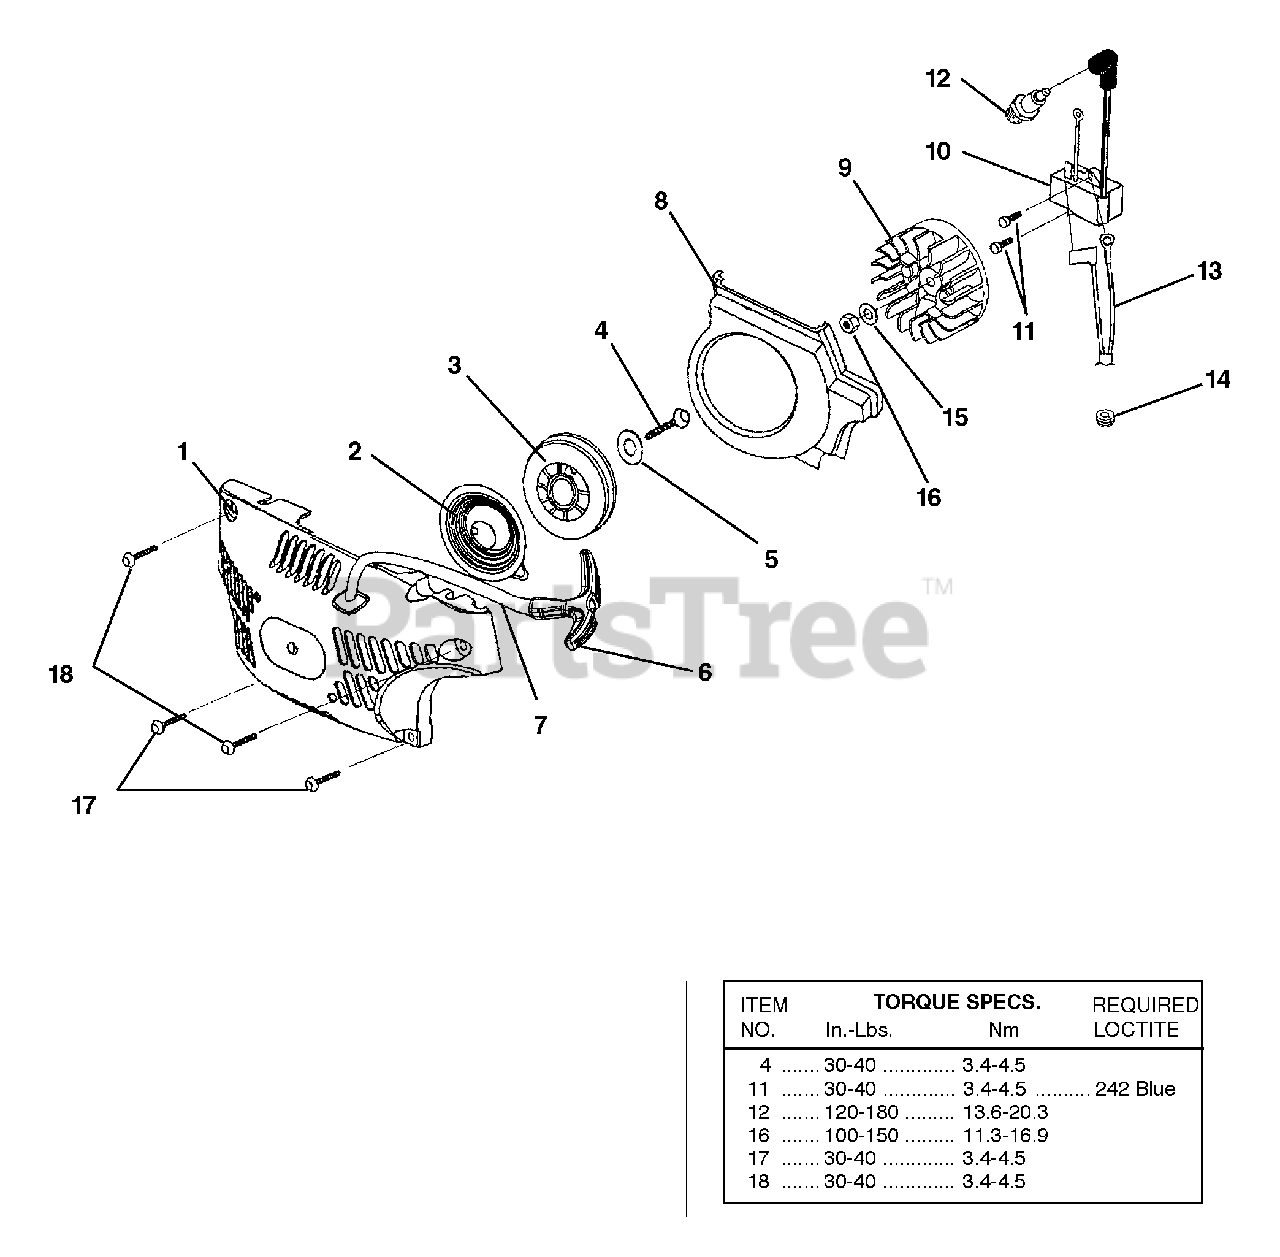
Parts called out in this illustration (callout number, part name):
1	Starter Kit
2	Spring & Container
3	Pulley, Starter
4	Screw, Thread Form, Plastite (10-14 x 5/8")
5	Washer, Retaining
6	Grip, Starter
7	Rope, Starter 46"
8	Baffle, Fan Housing
9	Rotor & Starter Pawl
10	Ignition Kit (33cc models)
11	Screw, Thread Form (8-32 x 5/8")
12	Spark Plug
13	Ignition Switch Harness
14	Grommet, Wire Harness (Split)
15	Washer, Flat
16	Nut, Jam
17	Screw, Truss Hd., Plastite (10-14 x 7/8")
18	Screw, Truss Hd., Plastite (10-14 x 5/8")
